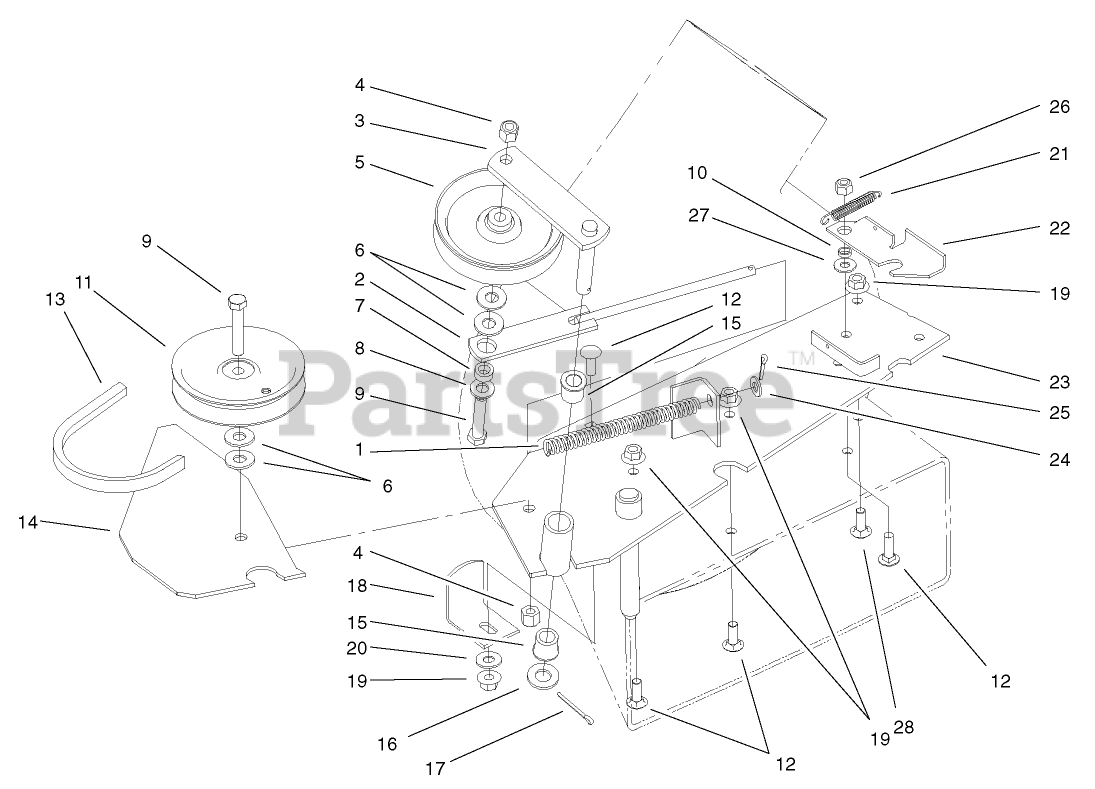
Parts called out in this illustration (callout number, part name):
1	SPRING-COMPRESSION
2	SPRING-ROD
3	IDLER ARM ASM
4	NUT-LOCK, NI
5	PULLEY-IDLER
6	WASHER-FLAT
7	SPACER
8	WASHER-FLAT
9	SCREW-HH
10	BUSHING
11	PULLEY-IDLER
12	SCREW-CARR
13	BELT-V
14	SUPPORT-SHIELD, BELT
15	BUSHING
16	WASHER-FLAT
17	PIN-COTTER
18	BRACKET-SUPPORT, HOUSING
19	NUT-HF
20	WASHER-FLAT
21	SPRING-EXTENSION
22	LATCH-BLOWER
23	MOUNTING-BLOWER
24	WASHER-PLAIN
25	PIN-COTTER
26	NUT-LOCK, NI
27	WASHER-FLAT
28	BOLT-CARR
